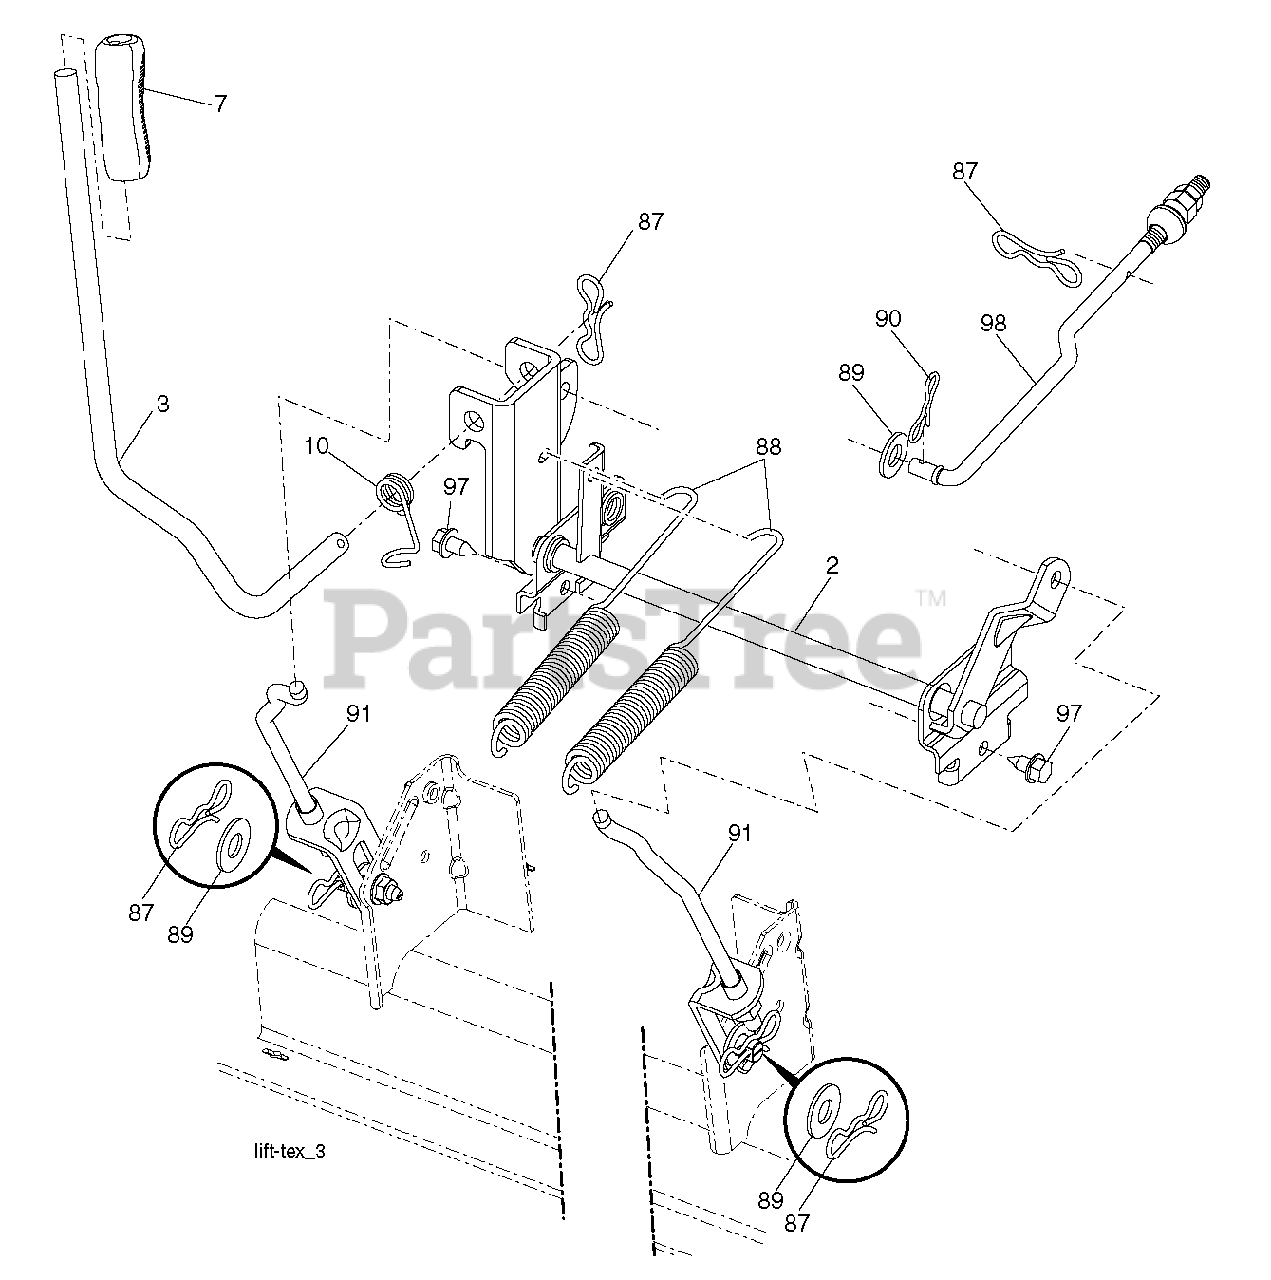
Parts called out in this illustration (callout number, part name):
2	SHAFT.ASM.CROSS.LIFT
3	LEVER.LIFT.HANDLE.LT
7	GRIP.HANDLE.LIFT.PVC.BLACK
10	SPRING.TORSION.LIFT.HANDLE
87	PIN.COTTER.7/16.BOW TI.
88	SPRING.LIFT.ASSIST
89	WASHER.CLEAR.ZINC
90	PIN.COTTER.5/16.BOW TI
91	LINK.ASM.LIFT.REAR
97	SCREW, 3/8-16X3/4
98	LINK.ASM.SUSP.FRONT.MWR.10.5
